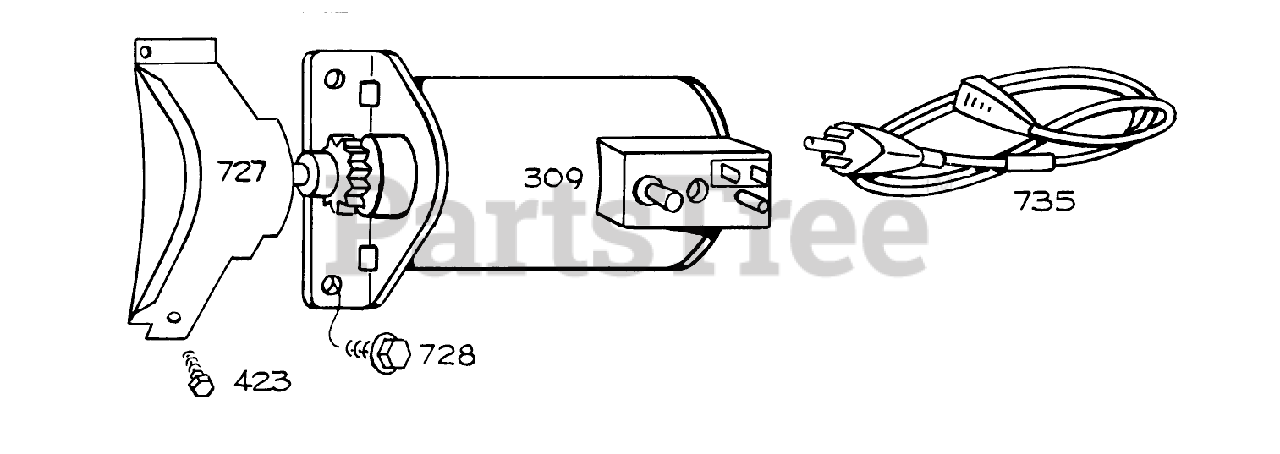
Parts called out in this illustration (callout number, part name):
309	Motor-Starting
423	B S No. 299967 (**)
423	Screw
727	Commutator End Cap Assy. including Bushing, Brushes and Springs.
727	Starter Pinion Cover
728	B S No. 390098 (*)
728	Screw
735	B S No. 299965 (**) Thru Bolt Assembly includes Nuts and Lockwashers.
735	Cord-Starter
763	B S No. 390080 (*) B S No. 299962 (**) Rectifier Assembly including Switch, attached Brush and Gasket. B S No. 390099 (*) B S No. 299966 (**)
763	Electric Starter Kit-110 Volt (Bendix)
